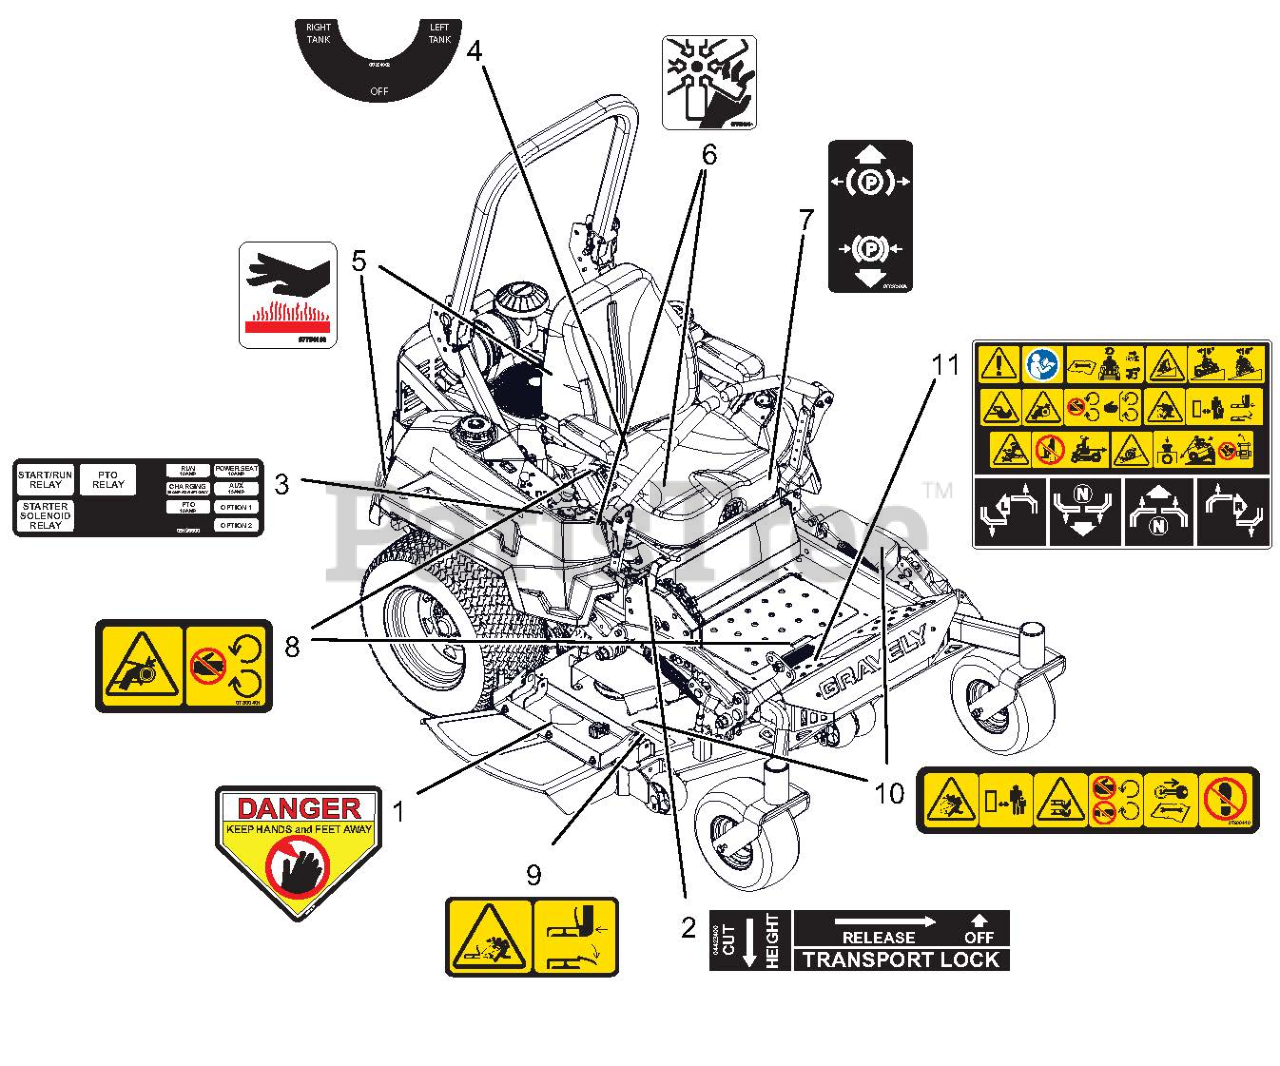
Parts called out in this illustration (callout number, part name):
1	DECAL, DANGER
2	DECAL, TRANSPORT LOCK INSTR
3	DECAL, PT200/400 FUSE BOX
4	DECAL- FUEL CONTROL VALVE
5	DECAL, HOT SURFACE
6	DECAL, DANGER FAN
7	DECAL, PARKING BRAKE LEVER
8	DECAL, SAFETY - GUARDING
9	DECAL, SAFETY - DECK GUARDING
10	DECAL, DECK SAFETY
11	DECAL, INSTR SAFETY
